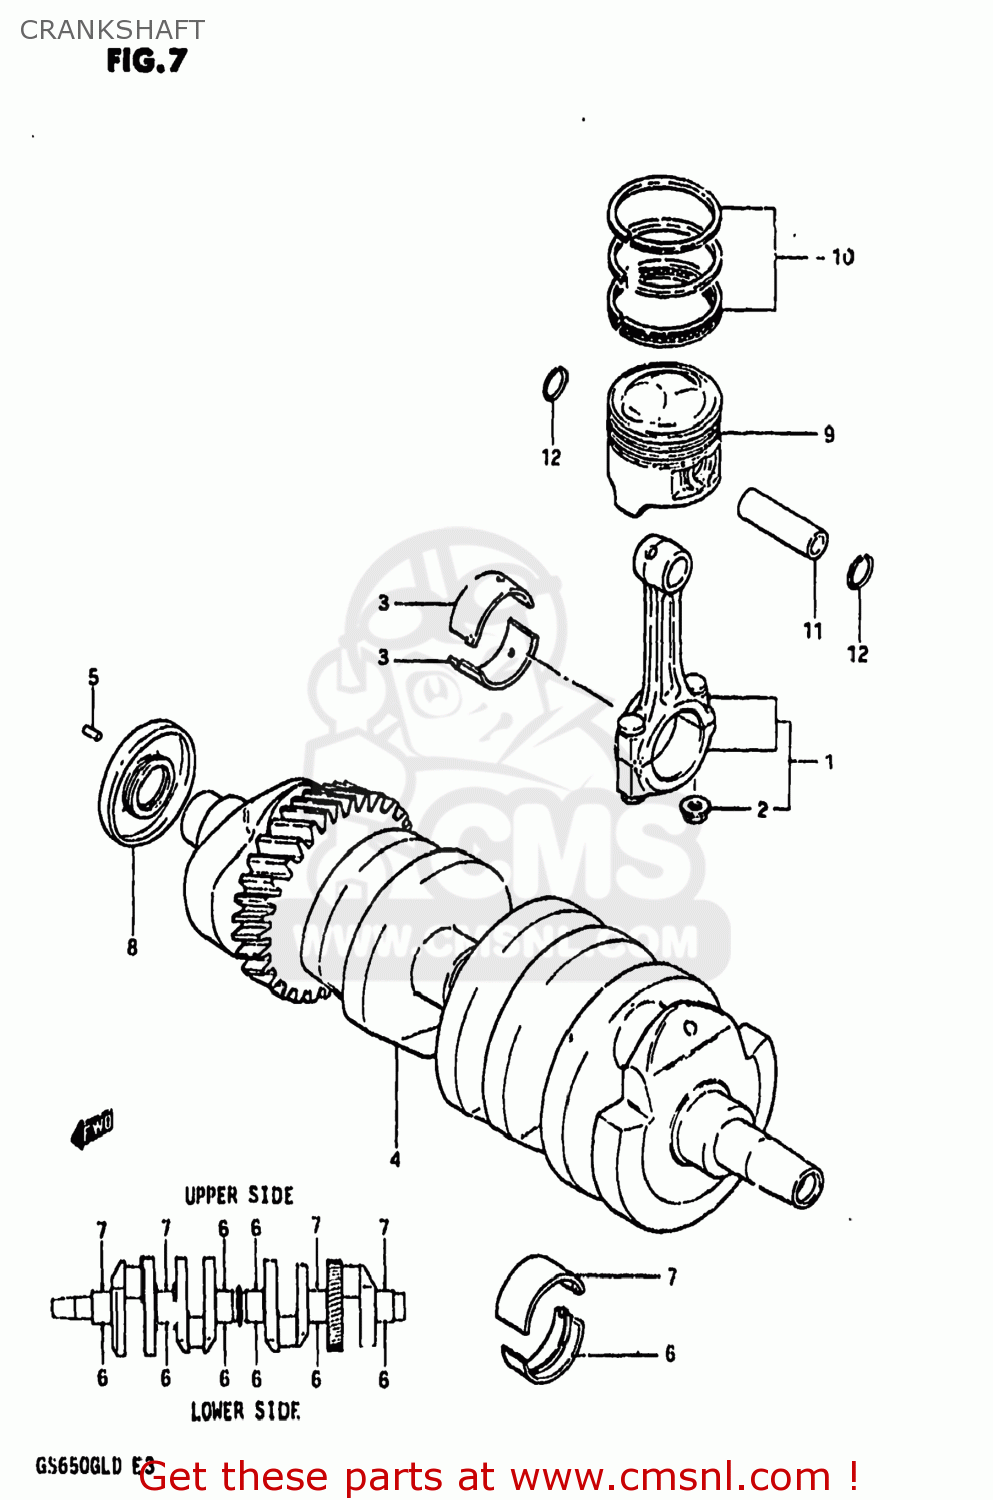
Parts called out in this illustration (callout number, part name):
1	ROD ASSEMBLY,CONNECTING
2	NUT
3	BEARING,CRANK PIN
4	CRANKSHAFT ASSEMBLY
5	PIN
6	METAL CRANKSHAFT
7	METAL CRANKSHAFT
8	OIL SEAL
9	PISTON
10	RING SET,PISTON
11	PIN,PISTON
12	CIRCLIP
